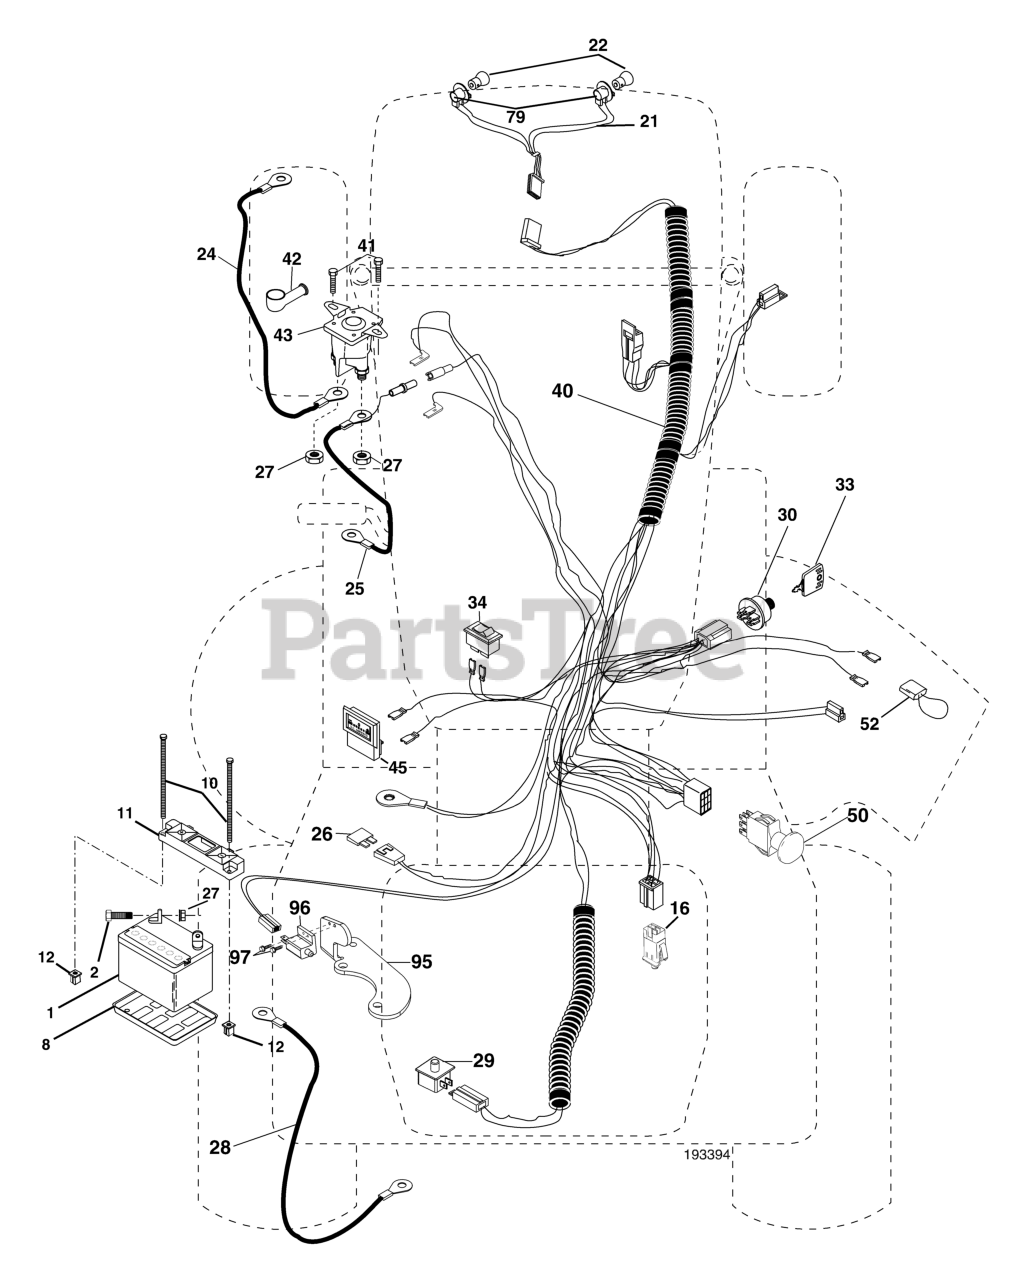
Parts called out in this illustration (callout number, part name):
1	BATTERY 12V .35 AMP
2	BOLT.HEX.1/4.X.3/4.DICHROMATE
8	BATTERY TRAY T
10	BOLT 1/4-20 X 7.5
11	BATTERY HOLDDOWN FRONT MOUNT
12	NUT, PUSH NYLON 1/4" BATTERY
16	SWITCH INTERLOOK PUSH-IN
21	HARNESS.W/LIGHT SOCKET
24	CABLE.STARTER.6GA.22"RED
25	CABLE, BATTERY
27	NUT
28	CABLE, GROUND
29	SWITCH.SEAT.DP W/RAMPS
30	SWITCH.IGN.DELTA.W.LGH.ROS
33	KEY MLD GEN DELTA
40	HARNESS.IGN.REG.RECT
41	SCREW
42	TERMINAL COVER
43	SOLENOID
50	RP.SWTICH.PTO.8.TERMINAL
52	WIRE PROTECTION LOOP
79	BULB HOLDER ASM.
95	BRKT.ROS.6SP
96	SWITCH-INTER. GT
97	SCREW.TT.#10-32X.5.3/8.FLANGE
